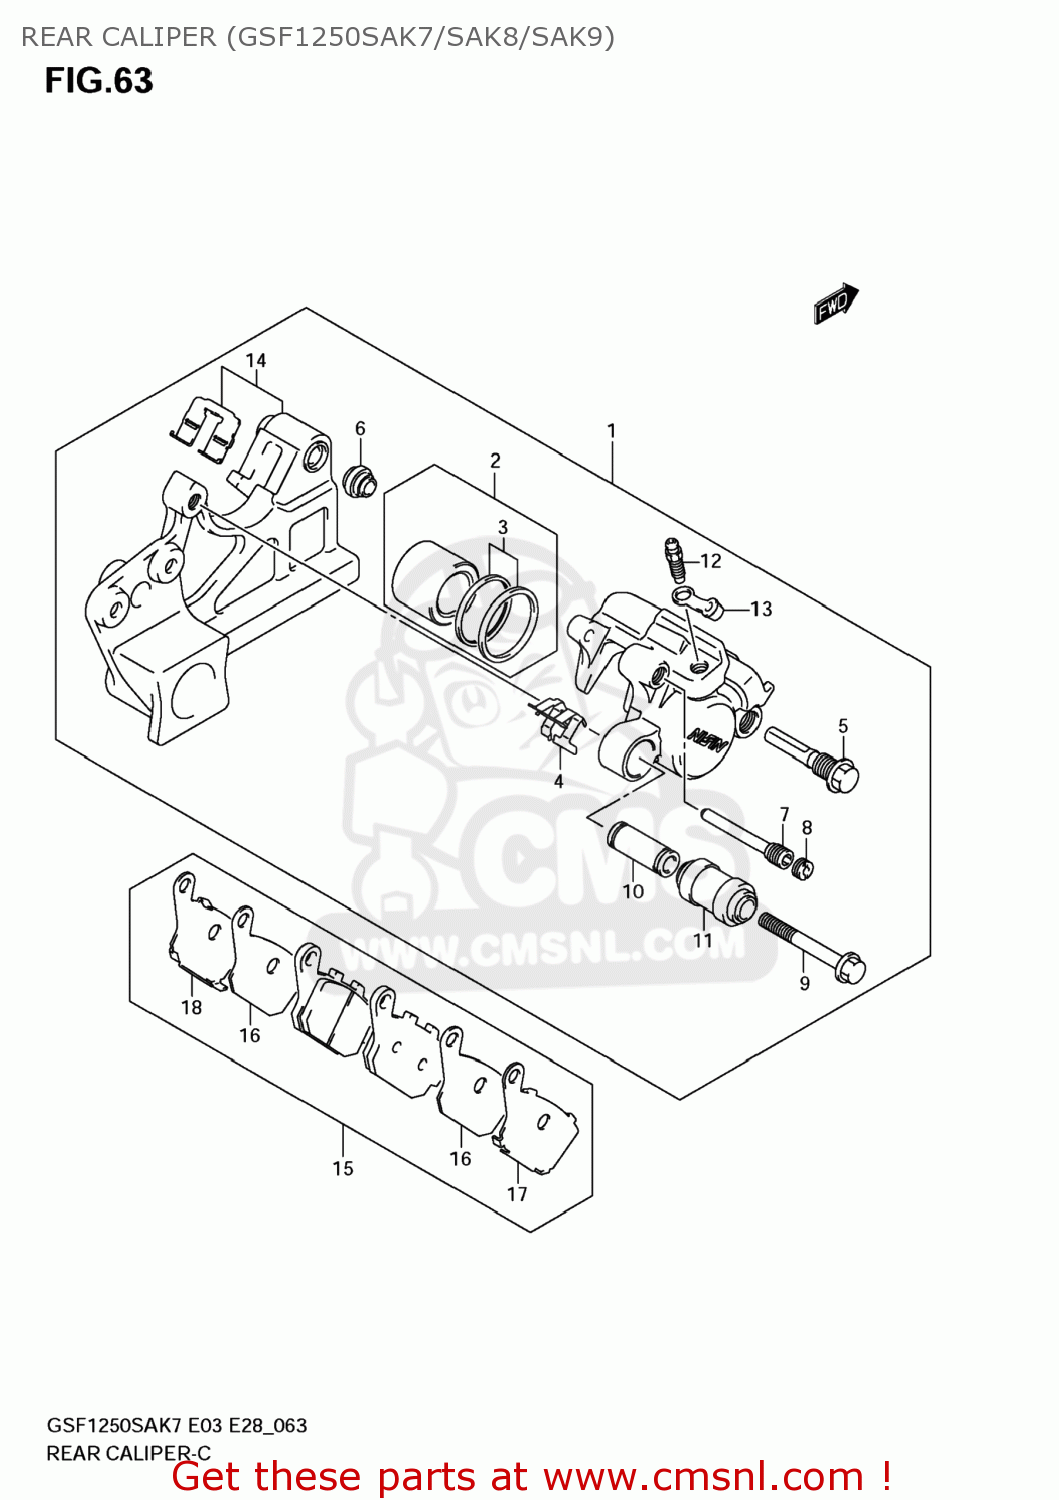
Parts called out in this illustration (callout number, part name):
1	REMZUIGER SET
2	PISTON SET
3	SEAL SET,PISTON
4	SPRING,PAD
5	BOLT
6	BOOT
7	PIN,PAD
8	PLUG,PIN
9	BOLT
10	SLEEVE
11	BOOT,SLEEVE
12	BLEEDER
13	CAP,BLEEDER
14	BRACKET
15	PAD & RETAINER
16	INSULATOR
17	RETAINER
18	RETAINER
